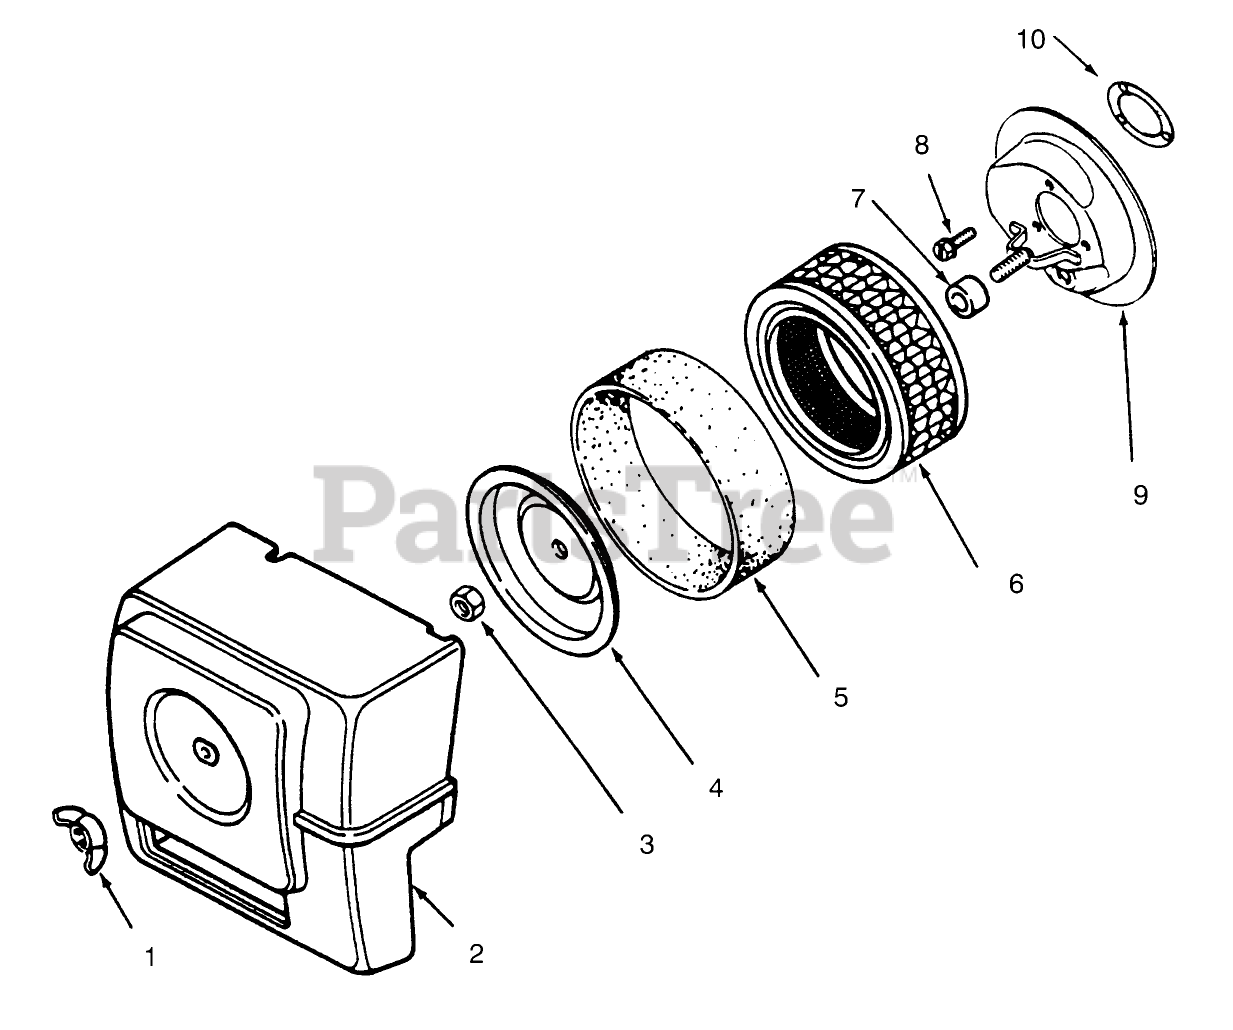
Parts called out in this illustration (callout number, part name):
1	KOHLER X-276-7
2	KOHLER 47-096-10
3	KOHLER 41-100-04
4	KOHLER 52-082-04
5	KOHLER45-083-01
6	KOHLER 45-083-02
7	KOHLER 231032
8	KOHLER X-67-65
9	KOHLER 47-094-20
10	KOHLER 45-041-07
